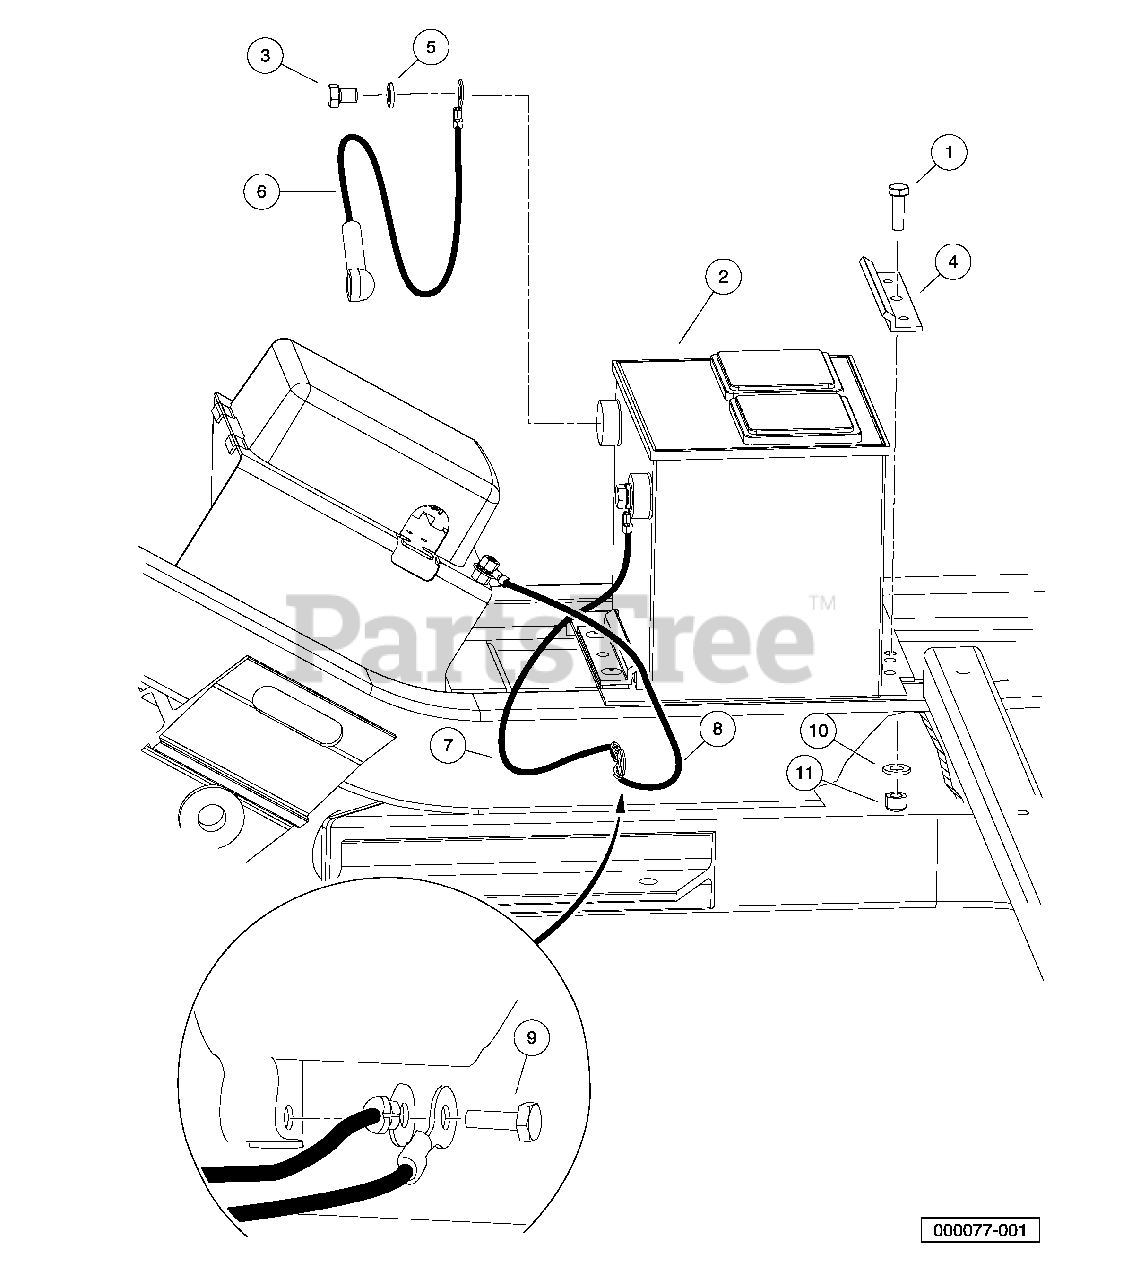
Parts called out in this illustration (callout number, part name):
1	Screw, 5/16-18 X 1.00 Hex Cap
2	Battery, 12-Volt
3	Screw, 3/8-16 X 0.50 Stainless Steel Hex-Head
4	Clamp, Battery
5	Lockwasher, 3/8 Stainless Stl
6	Asm, #6 Red Wire
7	Asm, #6 Blk Wire
8	Asm, #6 Blk Wire
9	Bolt, M6 X 1 X 16 Loctite
10	Washer, 5/16 Type A Flat
11	Locknut, 5/16-18 Nylon Insert
